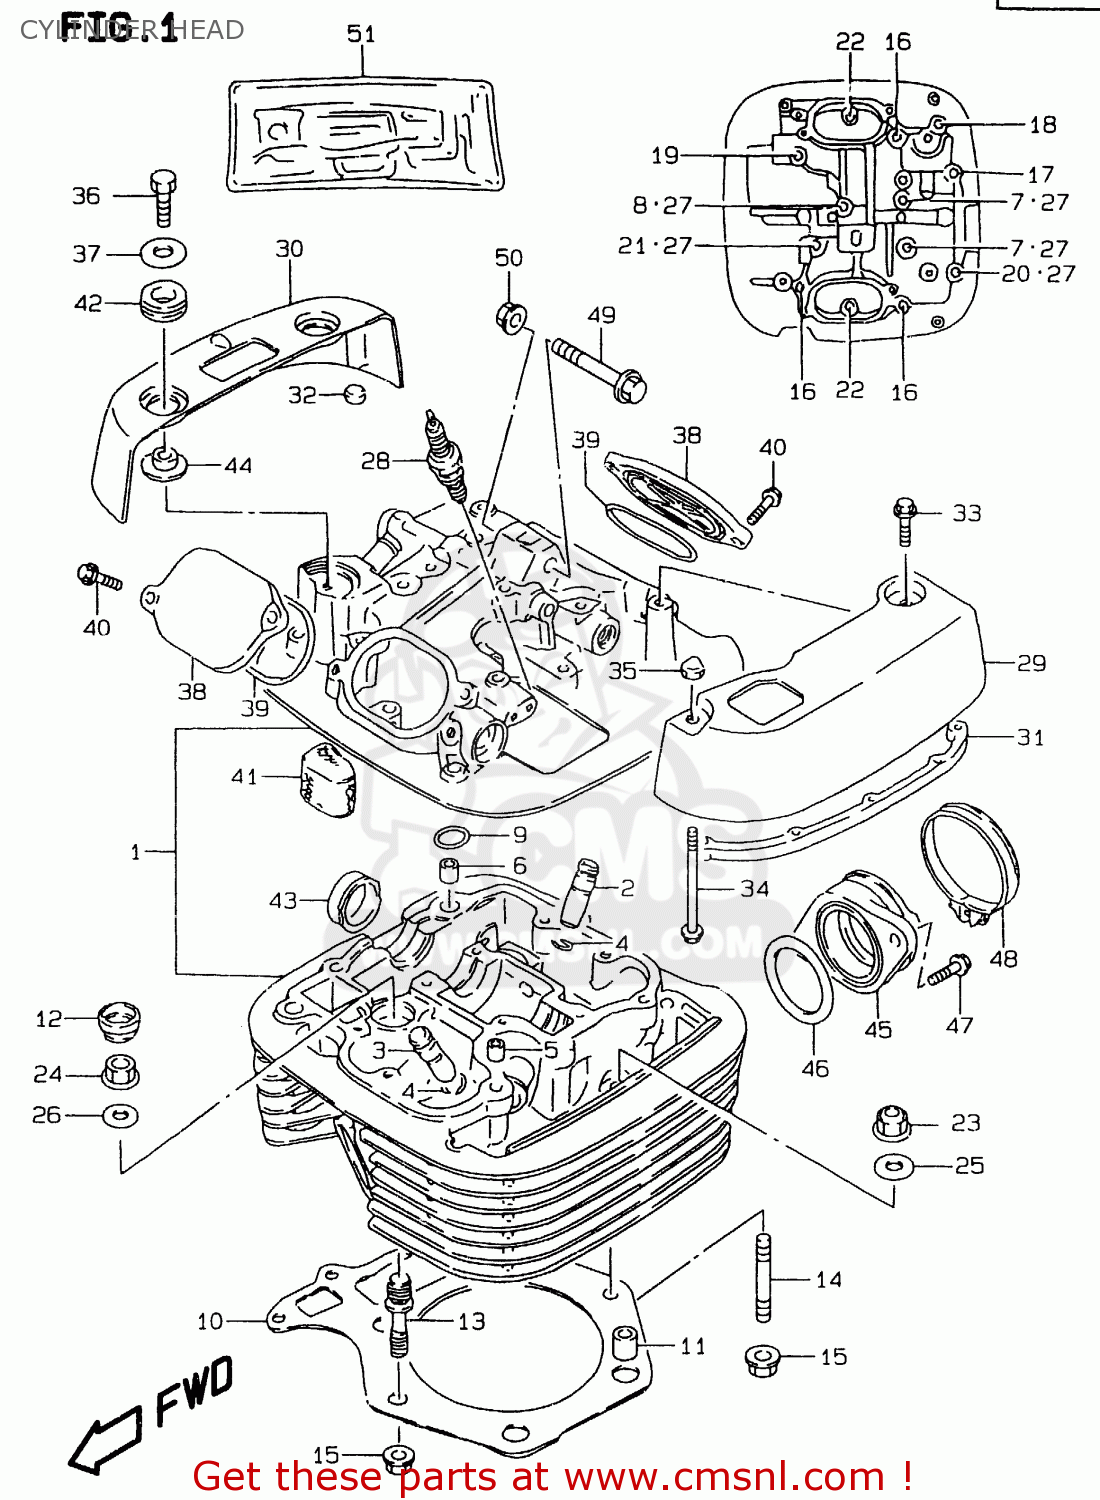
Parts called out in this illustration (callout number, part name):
1	HEAD ASSY,CYLINDER
2	GUIDE,VALVE
3	GUIDE,VALVE
4	RING,SNAP
5	PIN(6.2X8X11)
6	PIN(8.4X11X14)
7	BOLT(6X60)
8	BOLT(6X70)
9	O RING,CYL HEAD COVER
10	GASKET,CYLINDER HEAD (NAS)
11	PIN
12	CAP,CYLINDER HEAD SEAL
13	BOLT,STUD
14	BOLT,STUD(8X31)
15	NUT
16	BOLT(6X39)
17	BOLT(6X125)
18	BOLT(6X115)
19	BOLT(6X60)
20	BOLT(6X130)
21	BOLT(6X55)
22	BOLT
23	NUT
24	NUT
25	GASKET(10.2X20X2).3 (NAS)
26	GASKET(10.2X20X2).3 (NAS)
27	GASKET(5.8X13X1.2) (NAS)
28	PLUG,SPARK(DPR8EA-9)
29	CAP,HEAD COVER,L
30	CAP,CYLINDER HEAD COVER,R
31	CUSHION,HEAD COVER CAP,L
32	CUSHION,R CAP
33	BOLT
34	BOLT
35	NUT
36	BOLT
37	WASHER(6.5X24X1.6)
38	CAP,INSPECTION
39	O RING(D:2.4,ID:23)
40	BOLT
41	SEPARATOR,OIL BREATHER COVER
42	CUSHION
43	PLUG(OD:30)
44	BUSH
45	PIPE,INTAKE
46	O RING(D:2.4,ID:45.7)
47	SCREW
48	CLAMP
49	BOLT
50	NUT
51	GASKET SET (NAS)
